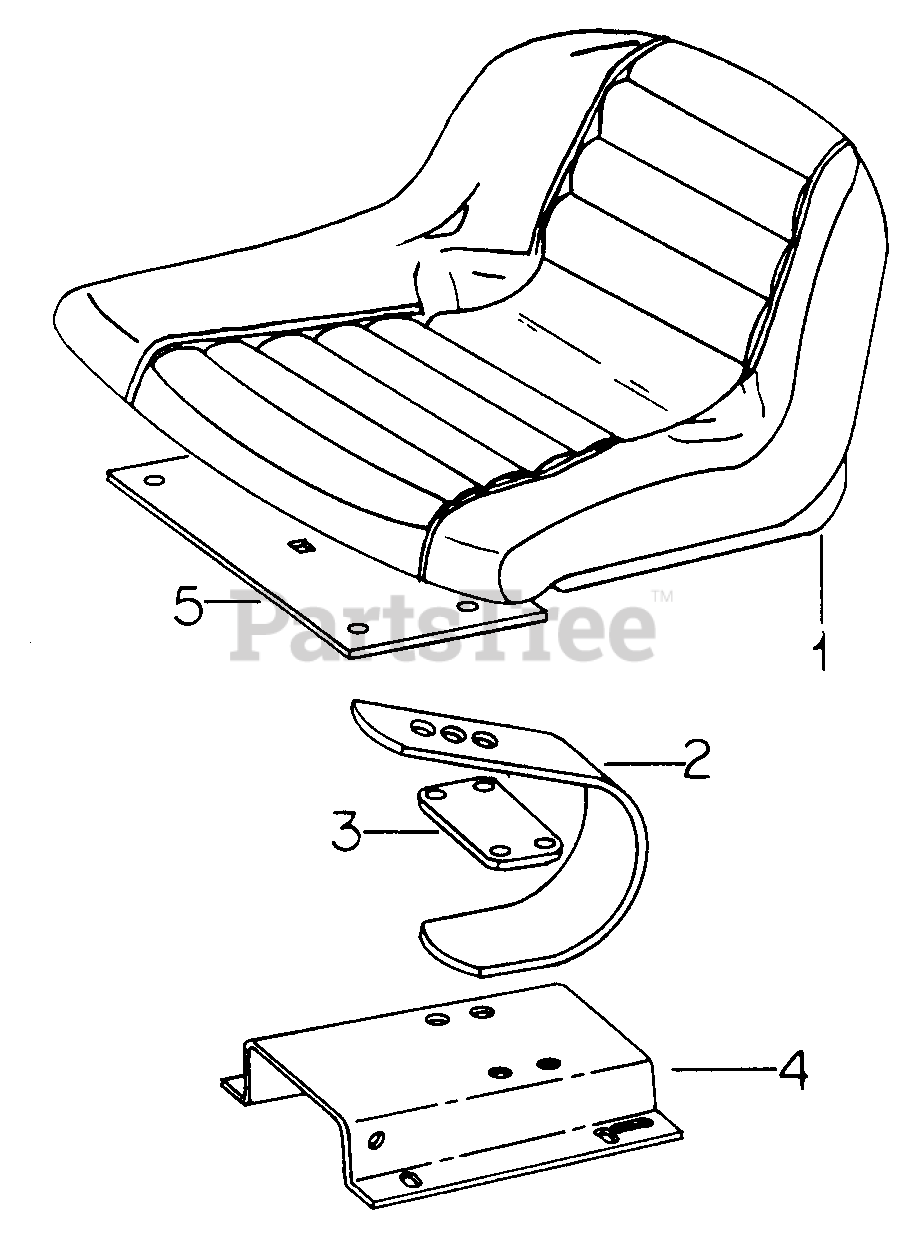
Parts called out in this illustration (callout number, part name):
1	Seat Assy
2	Spring, Seat Support
3	Plate, Seat Spring Clamping
4	Support Assy, Seat Spring
5	Bracket, Seat Mounting
